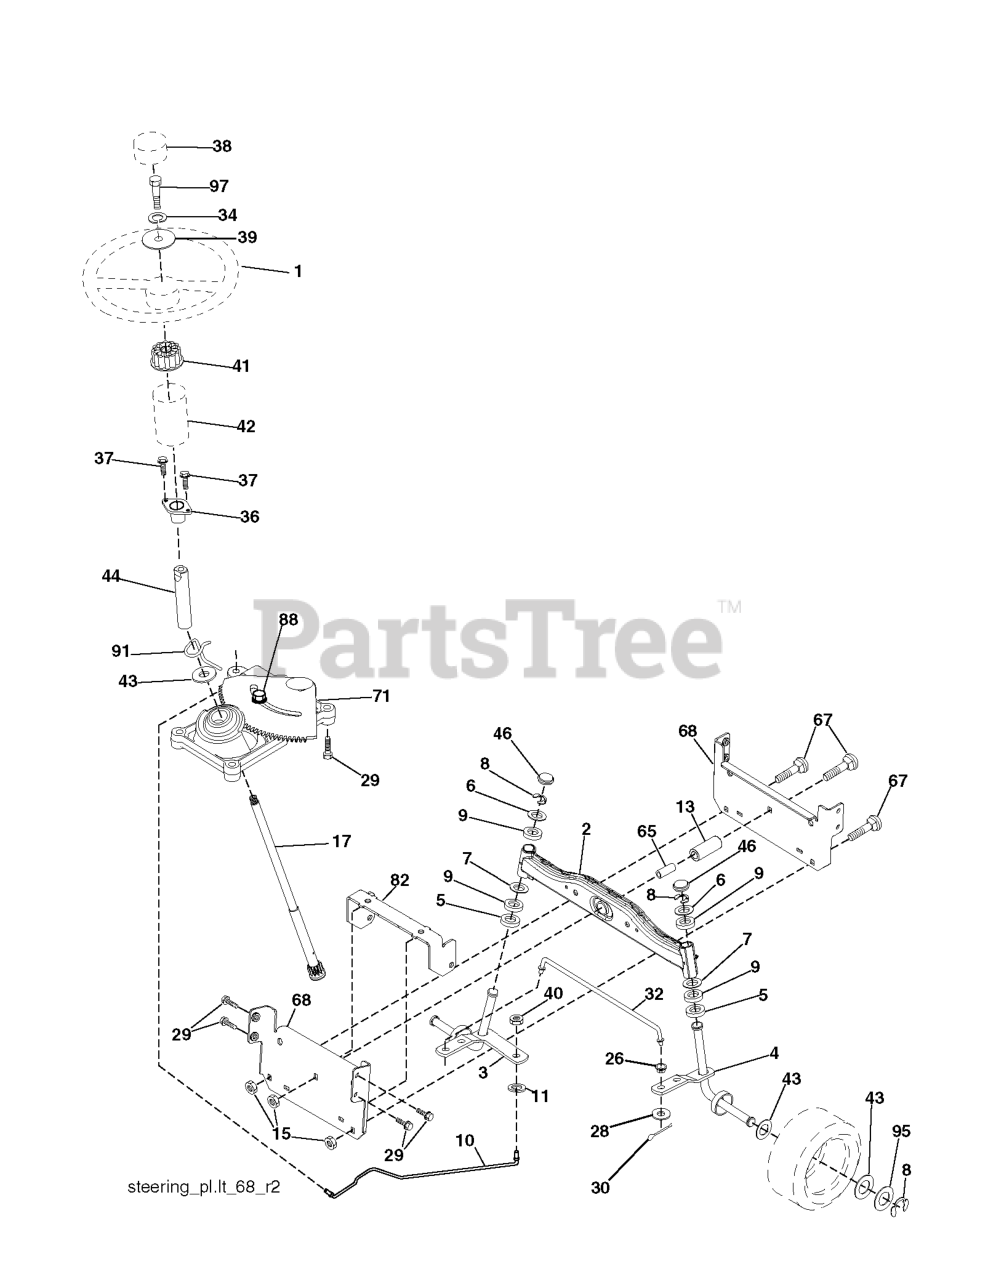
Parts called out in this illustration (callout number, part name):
1	WHEEL.STEERING.OPP.BLACK
2	AXLE.HALF.ASM.WELDED
3	SPINDLE.ASM.LH.15"TIRES
4	SPINDLE.ASM.RH.15"TIRES
5	THRUST WASHER
9	BRNG T
10	DRAGLINK.15".TIRES.2001
11	WASHER, LOCK 3/8
13	TUBE, PIVOT AXLE
15	NUT
17	SHAFT STEERING SPLINE
26	BUSHING.DRAGLINK (2 2)
28	WASHER
29	SCREW, 3/8-16X3/4
30	COTTER PIN
32	ROD.TIE.WIRE.FORM
34	WASHER.LOCK.HVY.HLCL.SPR.5/16
36	BUSHING, STEERING
37	SCREW.TT.#10-32X.5.3/8.FLANGE
38	CAP.WHEEL.STEER.OPP.BLK
39	WASHER.11/32
40	NUT CROWNLOCK 3/8-24
41	ADAPTER, WHEEL STNG..
42	BOOT.STEERING.SHAFT.BLACK
44	SHAFT.EXTEN.STRG.SPLINE
46	CAP.SPINDLE.BLACK
65	SPACER BRACE AXLE
67	BOLT CARRIAGE
68	BRACE.AXLE.15"TIRES
71	STEERING ASM
82	BRACKET.SUSP.CHASSIS.FRONT.15
88	BOLT, SHOULDER 7/16-20
91	CLIP.STEERING
95	WASHER.HARDENED
